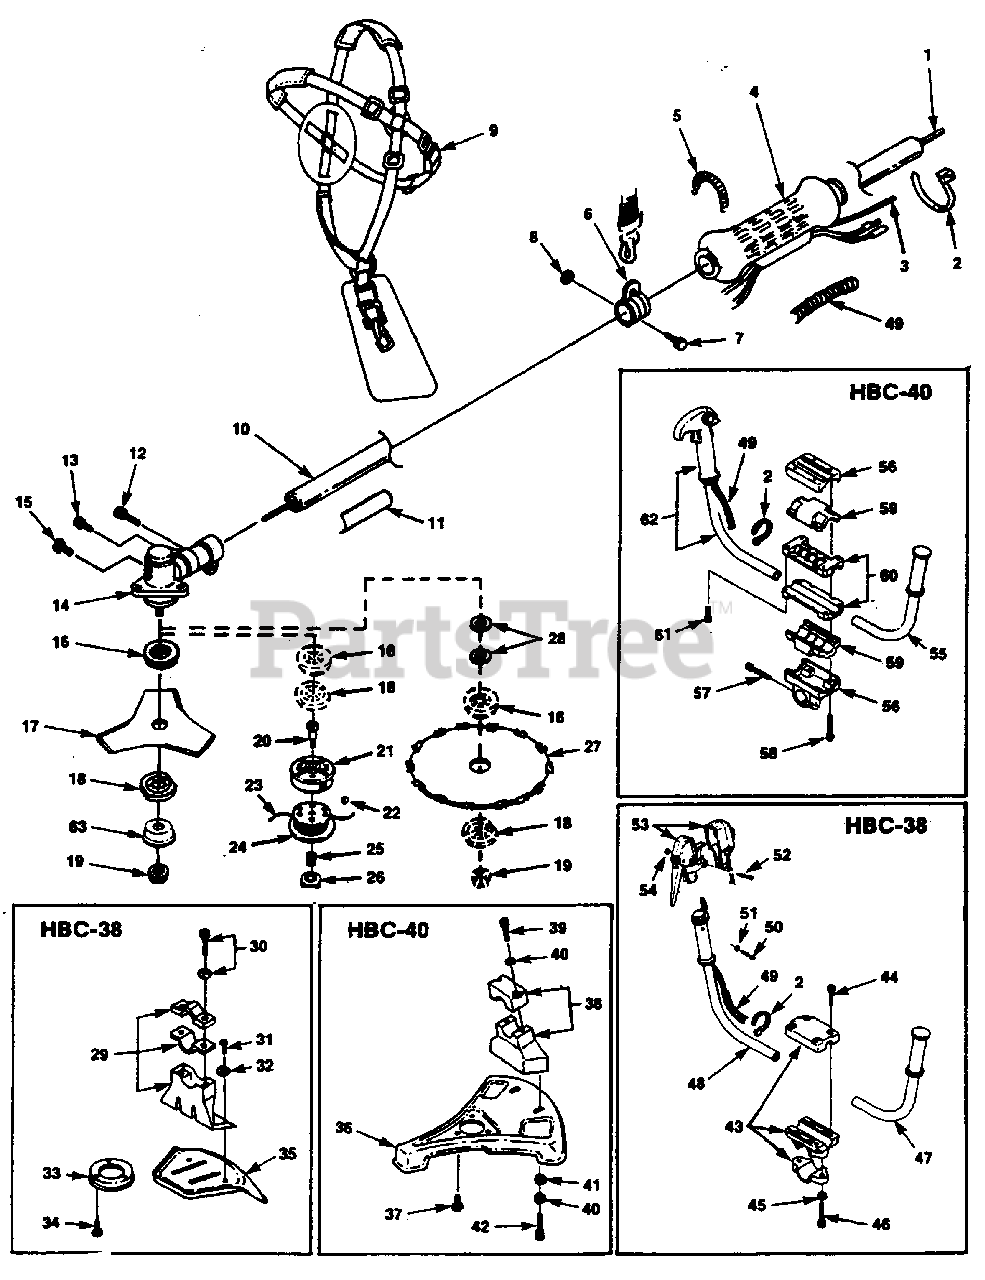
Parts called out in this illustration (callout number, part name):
1	DRIVE SHAFT
2	TIE- Cable
3	CABLE- Throttle
4	GRIP/HIP PAD
6	BAND- Hanger
7	BOLT & WASHER- Hanger
8	NUT-Hanger
9	HARNESS- Shoulder
10	HOUSING- Drive shaft
11	DECAL- Warning
14	GEAR HEAD
15	SCREW&WASHER-Grease
16	WASHER- Gear Head
17	BLADE- Tri-Arc
18	WASHER- Gear Head (flat)
19	NUT- Gear Head
20	CONNECTOR- Drive
21	HOUSING & EYELETS
22	EYELETS
23	STRING- Replacement (.105 Dia., 1 Ib. box)
24	SPOOL & STRING
26	NUT- Retainer
27	MACHETE BLADE KIT
36	GUARD- Blade
37	SCREW-Mach. (M5 x 10)
38	GUARD-Stand
39	SCREW- Socket (M6 x 1)
40	WASHER- Lock (M6)
41	WASHER- Flat (M6)
42	SCREW- Socket hd. (M6 x 12)
49	SLEEVING
55	HANDLE BAR- Left
56	HOUSNG ASSEMBLY
57	TUBING SCREW (M5 x 30)
58	HANDLE SCREW (M5 x 40)
59	JOINT- Rubber
60	CAST JOINT ASSEMBLY
61	JOINT SCREW (M5 x 25)
62	HANDLE BAR & THROTTLE (R.H.)
